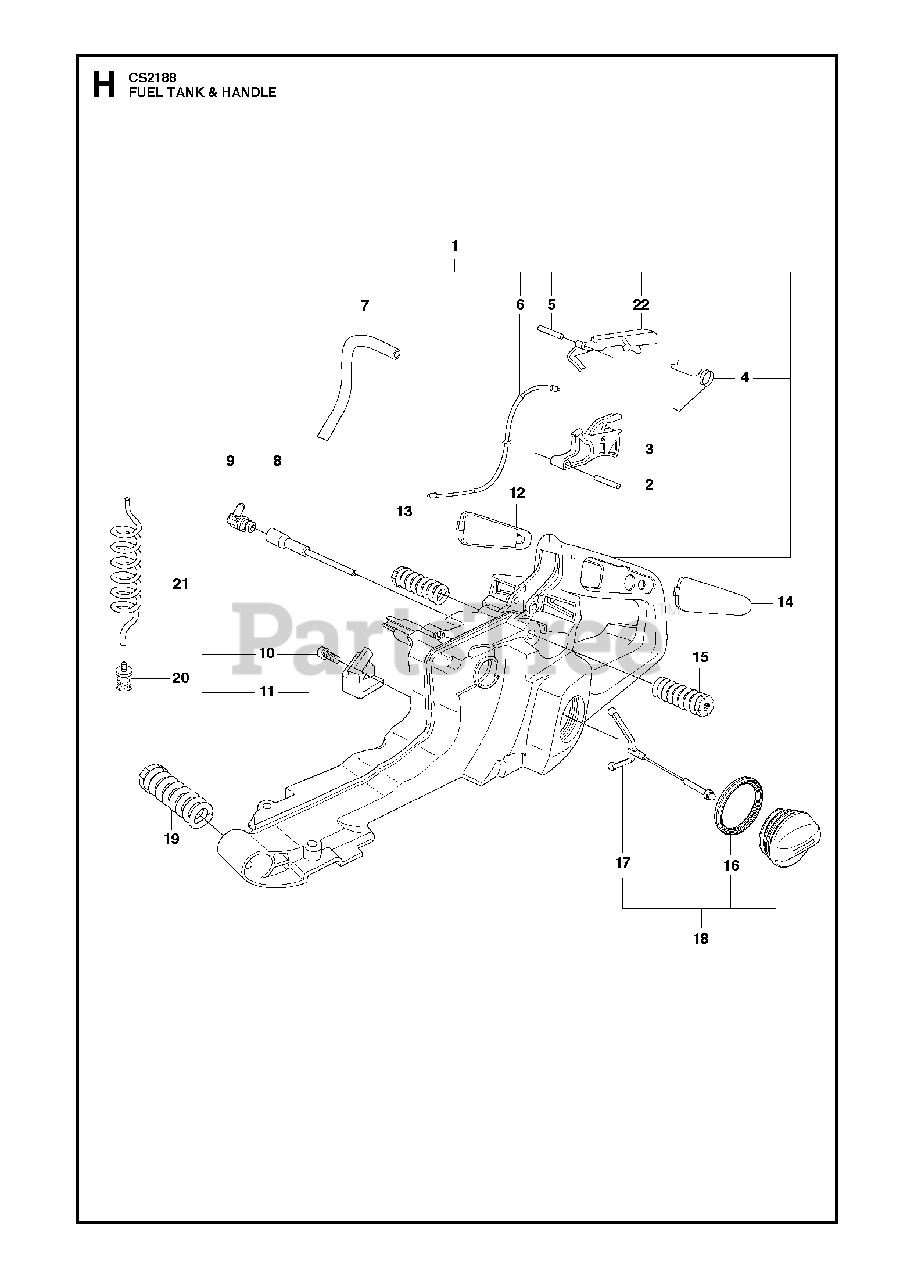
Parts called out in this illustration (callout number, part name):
1	TANK UNIT
2	PIN CPH8 4X20
3	THROTTLE TRIGGER
4	SPRING
5	PIN 3X25
6	WIRE
7	HOSE
8	TANK VALVE
9	CONNECTOR
10	SCREW
11	PROTECTOR
12	CLUTCH COVER
13	VIBRATION ABSORBER
14	CLUTCH COVER
15	VIBRATION ABSORBER
16	SEALING
17	HOLDER
18	TANK CAP
19	VIBRATION ABSORBER
20	FUEL FILTER
21	FUEL HOSE
22	THROTTLE LOCK
